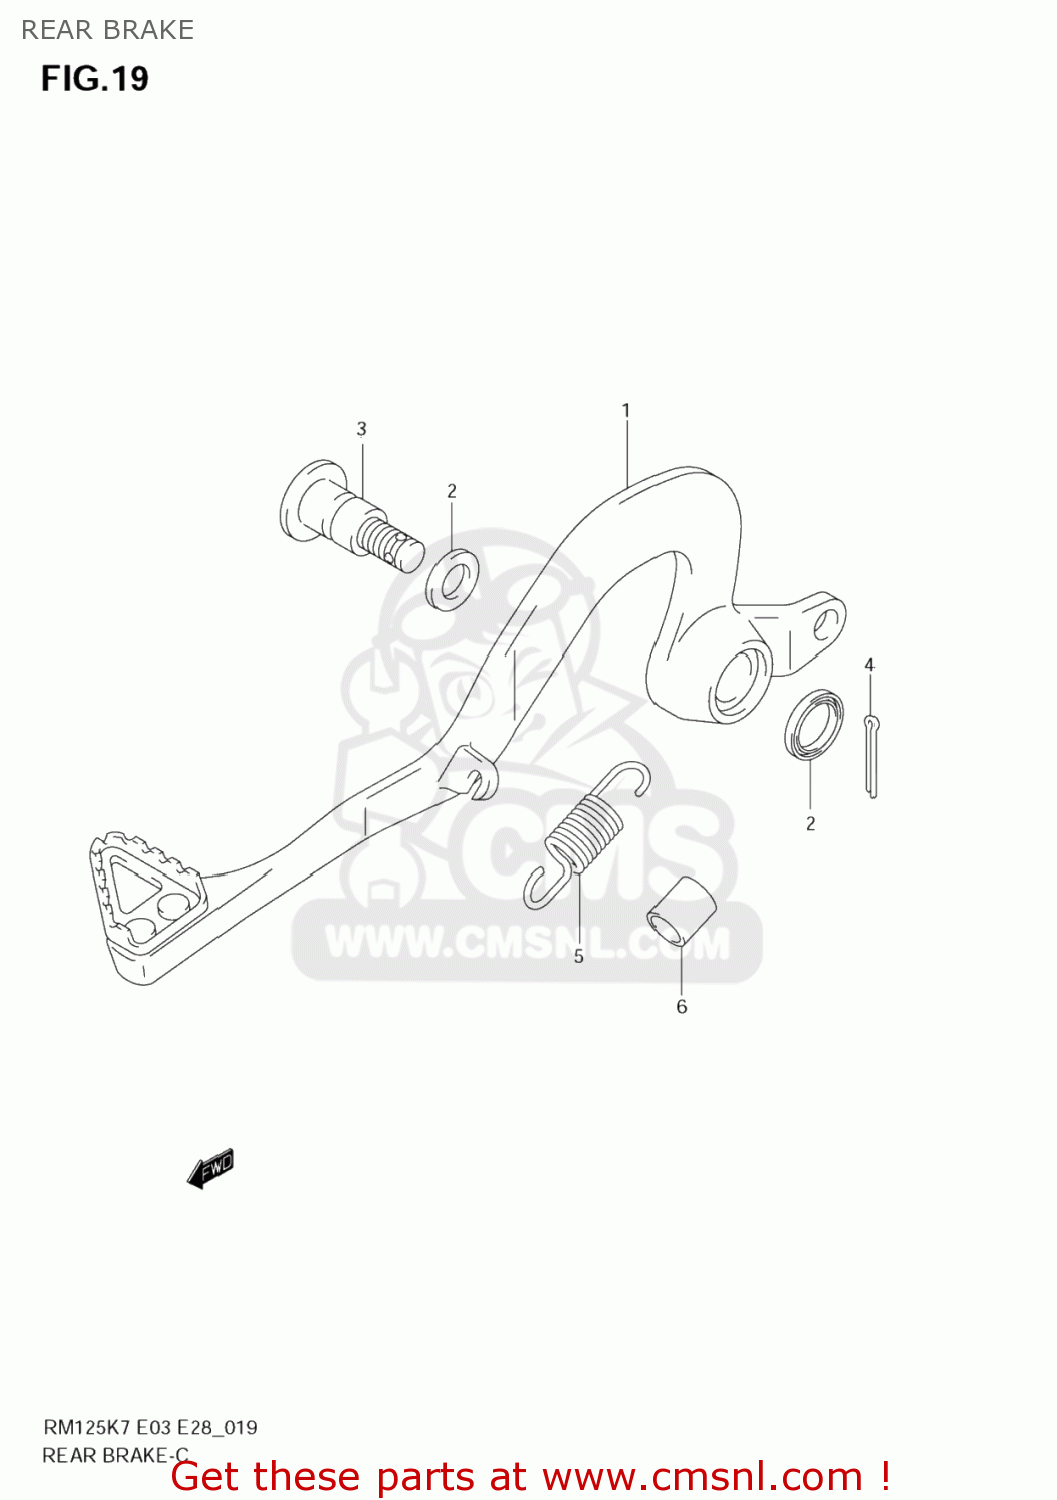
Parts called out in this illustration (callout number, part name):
1	PEDAL ASSY,BRAKE
2	SEAL,OIL(15X21X3)
3	SHAFT,BRAKE PEDAL
4	PIN
5	SPRING
6	PROTECTOR,SPRING
